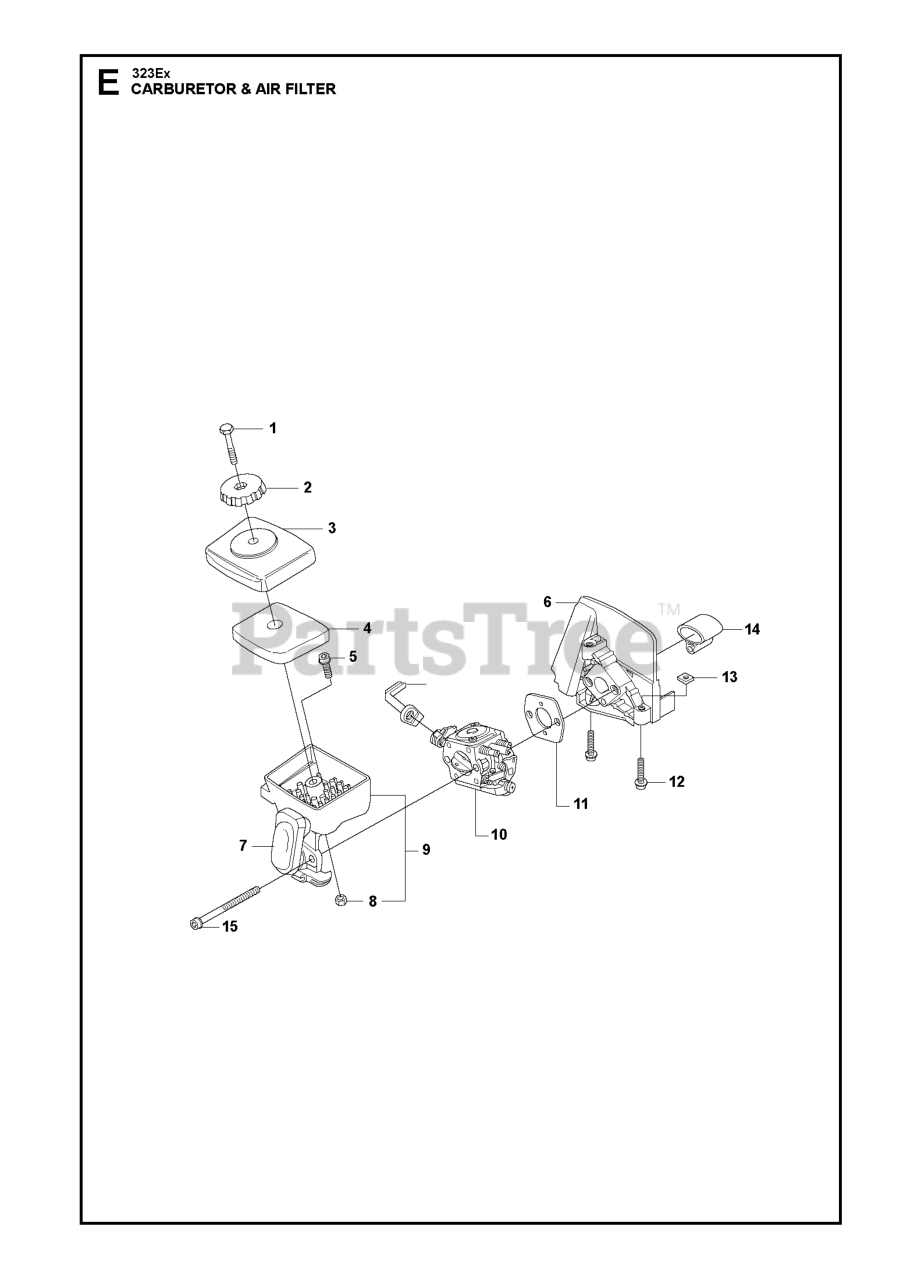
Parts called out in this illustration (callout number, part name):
3	AIR FILTER COVER
4	AIR FILTER (READY-OILED)
7	CAP FILTER HOLDER
9	FILTER HOLDER
10	CARBURETOR
